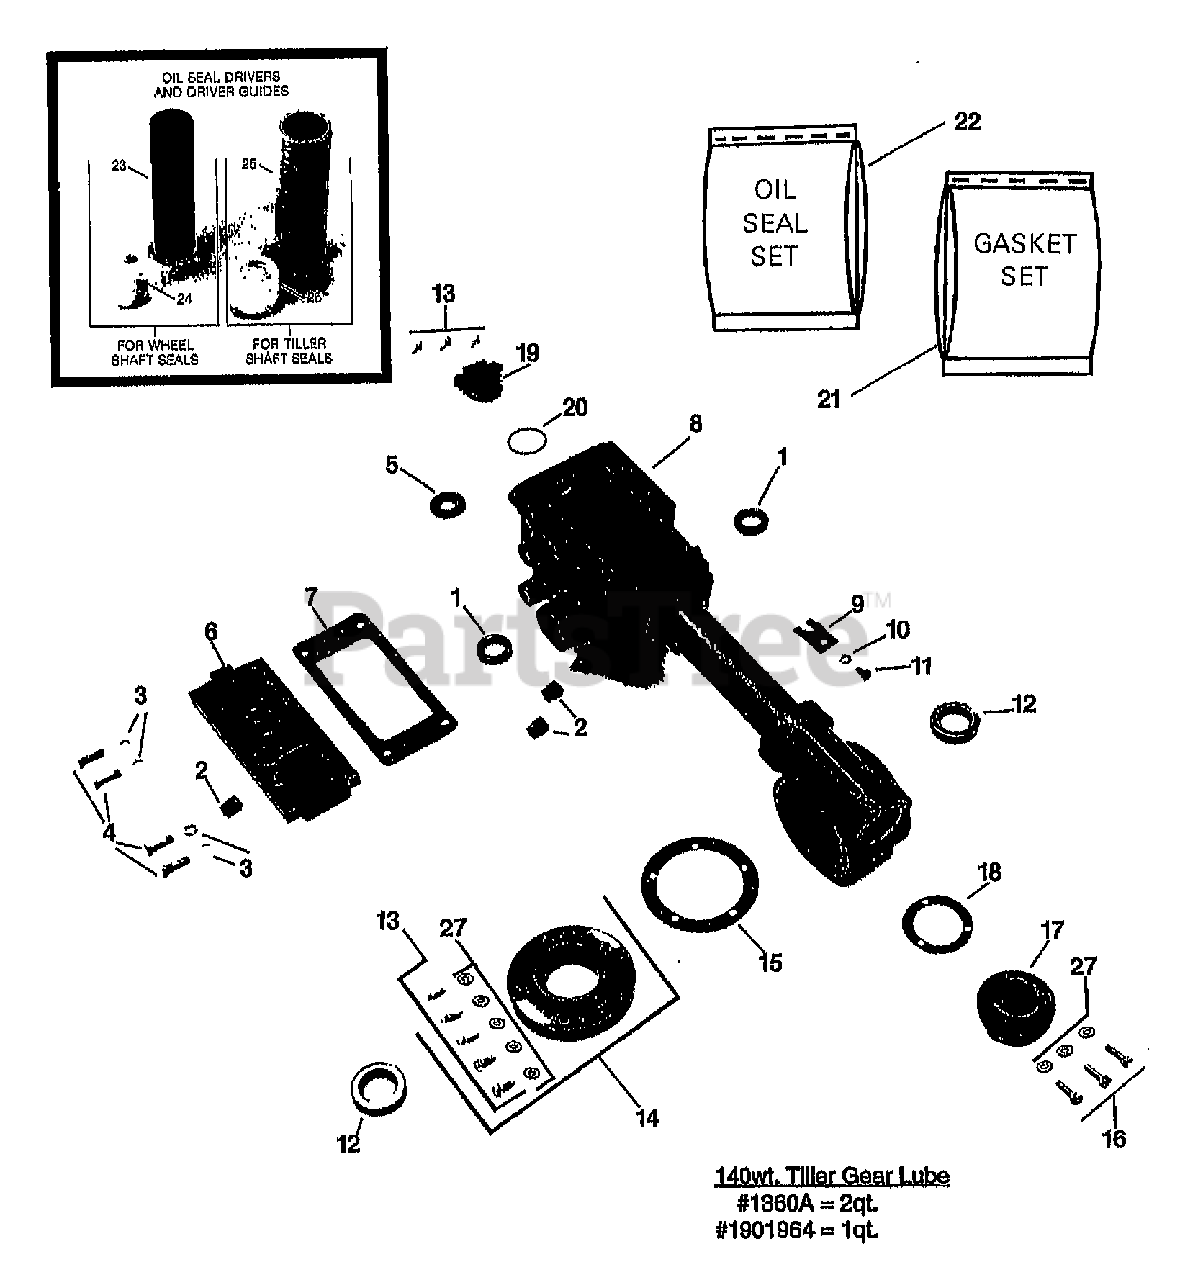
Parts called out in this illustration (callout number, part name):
1	SEAL-OIL WHEELSHAFT
2	PLUG-PIPE 3/8 NPT
3	WASHER-LK .312 ZP
4	SCR-HH 5/16-18X1.25 G5
5	SEAL-OIL PINION SHAFT
6	COVER-TRANS MACH
7	GASKET-TRANS HSG
8	ASSM-TRANS PONY 3-A UNIT (INCL. ONE #9402 REAR BEARING RACE)
9	PLATE-FRICTION
10	WASHER-LK .25
11	SCR-HH 1/4-20X.5 GR5 YEL
12	SEAL-OIL TILLERSHAFT
13	SCR-HH 1/4-20X.625
14	COVER-W/SCRS(TLR) (INCL. FIVE #9780)
15	GASKET-TILLER COVER (FITS ALL COVERS)
16	SCR-HFLK 1/4-20X.875
17	CAP-REAR #1115
18	GASKET-BRG COVER
19	COVER-FRONT BRG MACH
20	RING-O 1.625 ID
21	TRANS GASKET SET-PONY (UNIVERSAL)
22	SEAL-OIL (PONY)
23	OIL SEAL DRIVER-PLASTIC - (USE WITH PART #4921-2)
24	SEAL-DRIVER PILOT (USE WITH PART #4921-1)
25	H&P SEAL DRIVER (USE WITH PART #1961-2)
26	PILOT-SEAL DRIVER (USE WITH PART #1961-1)
27	WASHER - NYLON, NON-REUSEABLE
